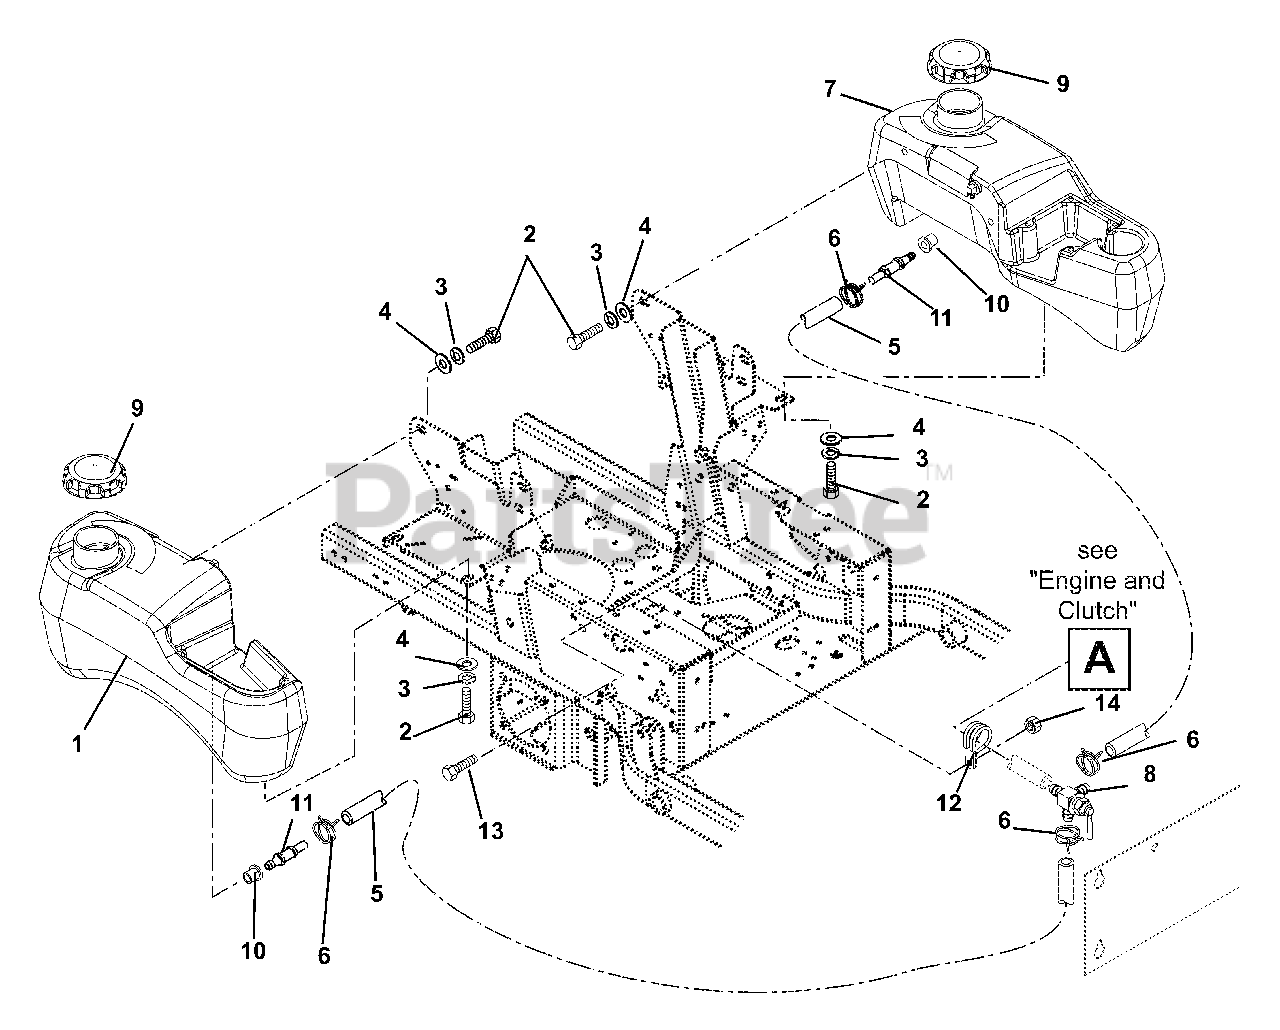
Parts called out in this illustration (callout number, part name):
1	TANK, GAS - RH W/O HOSE
2	@BLT-HEX .31-18X.75 GR5 YWZC
3	@WSHR-LK .31X.078 REG YWZC
4	@WSHR-FL-STL.38X.875X.083 YWZC
5	GAS LINE-BULK 1/4" I.D.
6	CLAMP-HOSE WIRE .490/.510X.116
7	TANK, LH FUEL 100 S. W/O HOSE
8	VALVE, FUEL
9	CAP - FUEL
10	BSHG-FLG .375 X 1.062 X .625 R
11	FITTING, TANK
12	CLAMP, CUSHIONED STEEL
13	@BLT-HEX .38-16X1.00 GR5 YWZC
14	@NUT-LK-TOP-FLG .38-16 YWZC
